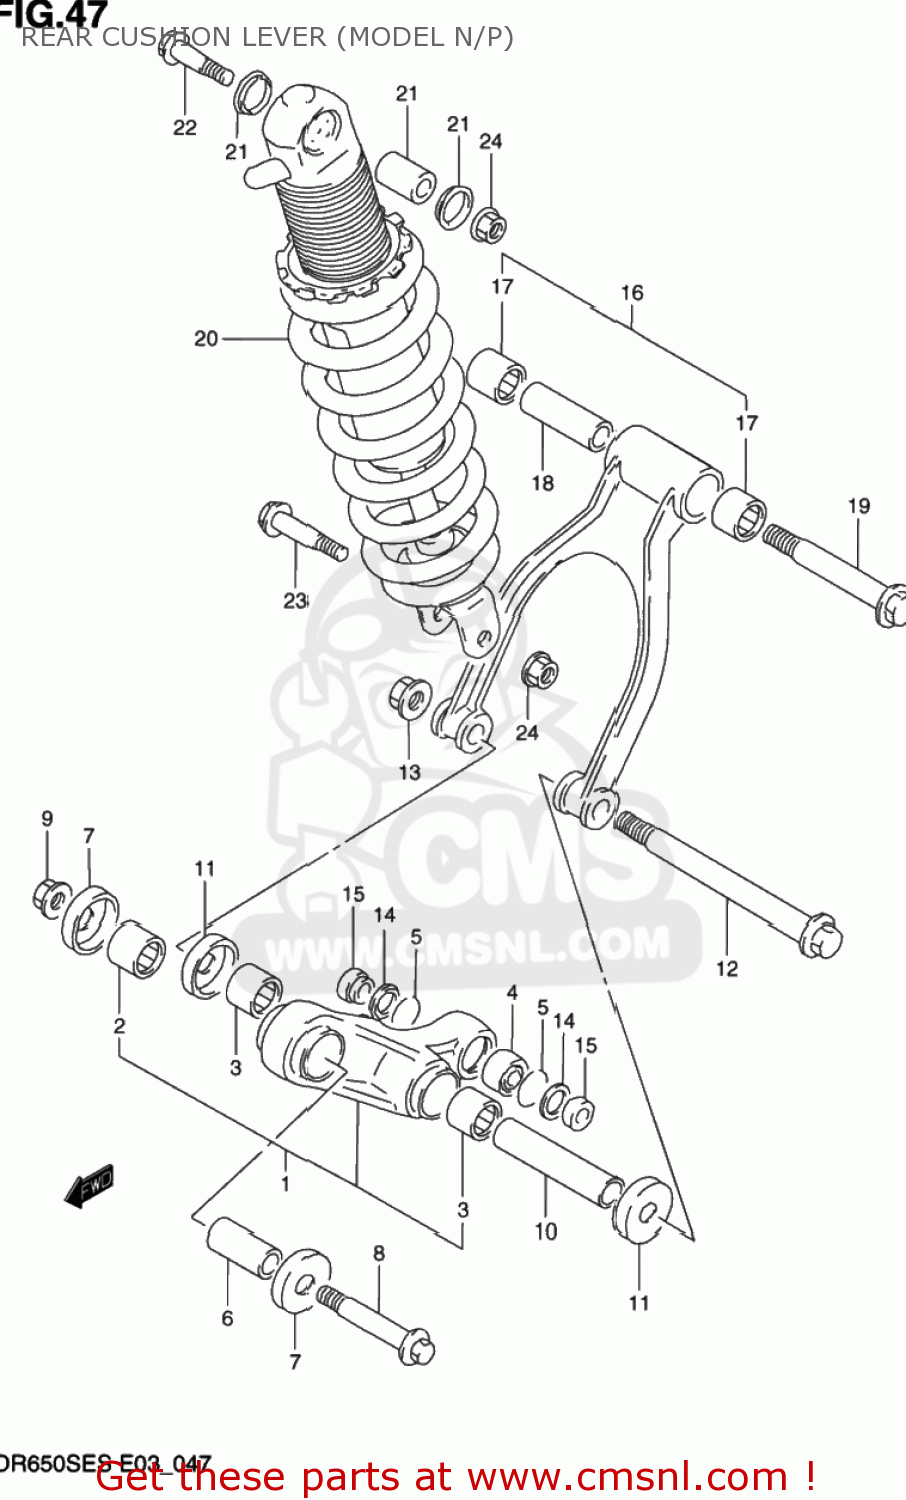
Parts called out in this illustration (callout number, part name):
1	LEVER SET,REAR CUSHION
2	BEARING(20X27X30)
3	BEARING(20X27X23.5)
4	BEARING,REAR SHOCK ABSORBER
5	RING
6	SPACER,RR CUSHION LEVER FR
7	SEAL,RR CUSHION LEVER FR DUST
8	BOLT,RR CUSHION LEVER FR
9	NUT 12MM
10	SPACER (14X20X78)
11	SEAL,RR CUSHION LEVER CTR DUST
12	BOLT,RR CUSHION ROD LWR
13	NUT
14	SEAL,DUST RR SHOCK ABSORBER
15	COLLAR
16	ROD SET,REAR CUSHION,LEFT
17	BEARING(20X27X23.5)
18	SPACER (14X20X63)
19	BOLT,RR CUSHION ROD UPR
20	ABSORBER ASSEMBLY,REAR SHOCK
21	COLLAR
22	BOLT(10X50)
23	BOLT(10X52)
24	NUT
